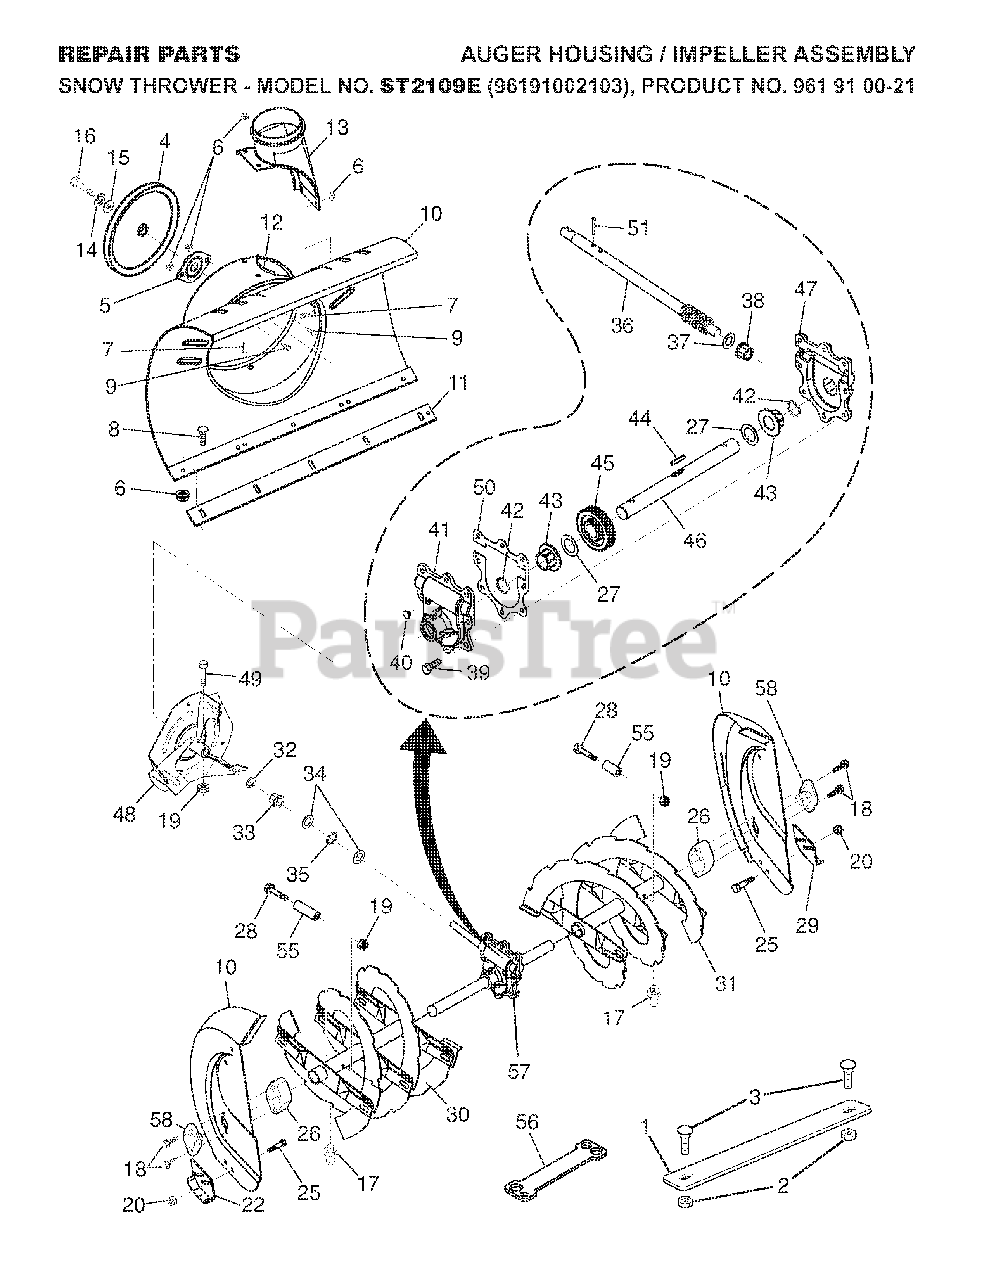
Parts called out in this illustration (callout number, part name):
1	WEIGHT, AUGER HOUSING 27
2	NUT, LOCK 5/16-18
3	BOLT.CARRIAGE.5/16-18
4	PULLEY, IMPELLER
5	BEARING FLANGE
6	NUT.FLANGE.5/16
7	BOLT.CARRIAGE.5/16-18X
8	BOLT
9	BOLT, HEX HEAD 5/16-18
11	SCRAPER BAR
12	BRACKET, CORNER DISCHARGE
13	BASE DISCHARGE CHUTE
14	LOCKWASHER
15	WASHER, FLAT
16	CAPSCREW.HX.HD.5/16-18X1.00.NY
17	GREASE FITTING
18	SCREW, HEX HD 5/16X1
19	LOCKNUT
20	NUT.FLANGE.5/16
22	SKID PLATE RH
26	BEARING RETAINER, PLASTIC
27	WASHER TRUST 1"
28	BOLT, SHEAR
29	SKID PLATE LH
30	AUGER ASSY-RH
31	AUGER ASSY-LH
33	BUSHING, FLANGE 3/4
34	WASHER, THRUST 3/4
35	BEARING TRUST 3/4
36	SHAFT, IMPELLER
37	WASHER, THRUST 5/8
38	FLANGE BUSHING-5/8
39	HEX SCREW-5/16 X 3/4
40	CASE PLUG
41	GEARBOX HOUSING-RH
42	OIL SEAL
43	FLANGE BUSHING-1"
44	KEY, SQUARE 1/4 X .875
45	WORM GEAR
46	AUGER SHAFT
47	GEARBOX HOUSING - LH
48	IMPELLER ASSY
49	SCREW.HEX.HD1/4-20X
50	GEARBOX GASKET
51	PIN, ROLL 3/16 X 1-1/8
56	RP WRENCH, SNOWTHROWER
57	GEARBOX.ASSEMBLY.AUGER
58	BEARING.BALL.AUGER.SHAFT
